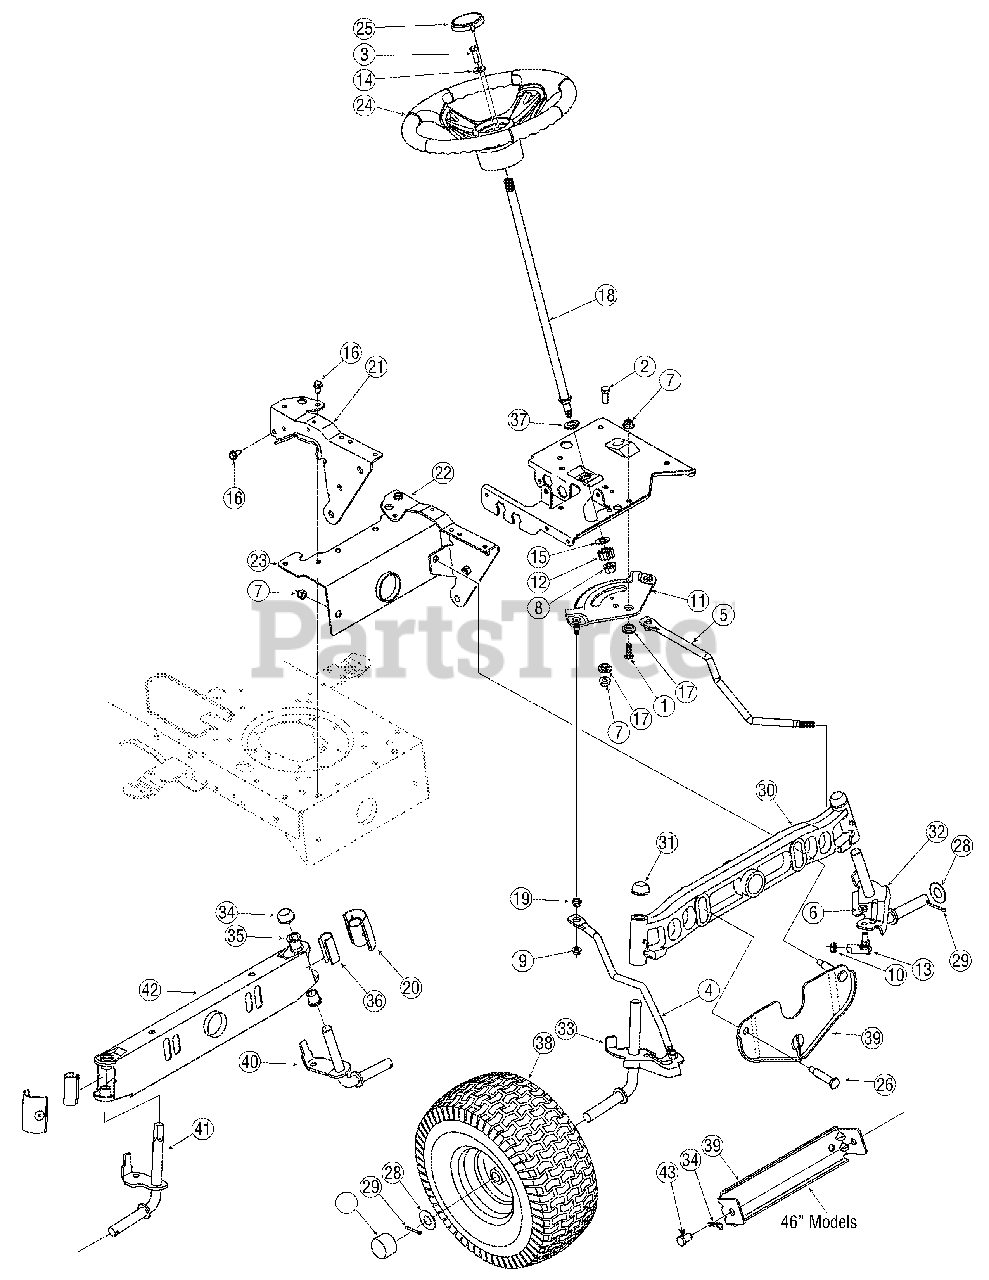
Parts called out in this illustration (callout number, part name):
1	Hex Screw, 3/8-16, 1.00, Gr5
2	Hex Screw, 3/8-16, 1.00, Gr5
3	Hex Screw, 5/16-18, 1.00, Gr5
4	Link, Drag, RH
5	Link, Drag, LH
6	Nut, Hex Lock, 3/8-24
7	Nut, Flange Lock, 3/8-16, Grf
8	Nut, Flange Lock, 7/16-20
9	Nut, Flange Lock, 5/16-18, Gr5
10	Nut, Jam, 7/16-20, Gr2
11	Gear, Steering, 11/90 Ratio
12	Gear, Pinion, Steering
13	Ball Joint, 7/16-20, Lock
14	Washer, Flat, .406 x .875 x .105
15	Washer, Flat, .51 x 1.12 x .06
16	Screw, 5/16-18, 0.750
17	Spacer, Shoulder, .38 x 1.00 x .31
18	Shaft, Steering, .625 OD x 24.25
19	Plastic Bushing .380 ID
20	Pivot Bar End Cap
24	Steering Wheel
25	Steering Wheel Cap
25	Steering Wheel Cap, Sprig Logo
25	Steering Wheel Cap, Tine Logo
26	Shoulder Bolt .5 x 2.38 3/8-16 42"
26	Shoulder Bolt .5 x 2.23 3/8-16
27	Hub Cap, Standard
28	Flat Washer, .781 x 1.59
29	Cotter Pin, 5/32 x 1.25
29	Washer, Flat .78 x 1.59 x .060
30	Cast Iron Pivot Bar
31	Push Cap
32	LH Axle Assembly, .750
33	RH Axle Assembly, .750
34	Cotter Pin, .080 x 1.5625 Internal
35	Flange Bearing
36	Axle End Cap, Standard
37	Hex Flange Bearing
40	LH Axle Assembly, .750
41	RH Axle Assembly, .750
43	Clevis Pin, .50 x .78 lg.
